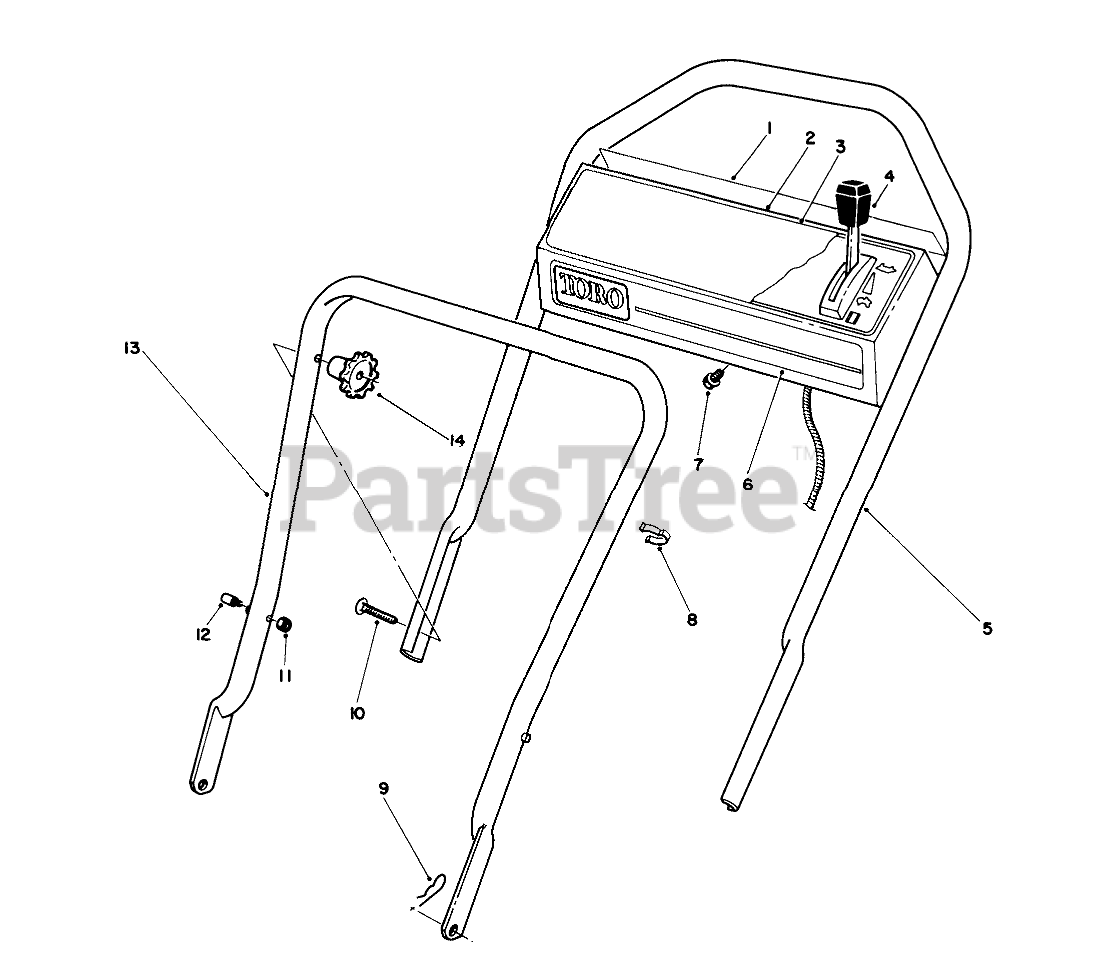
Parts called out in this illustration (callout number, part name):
1	DECAL - PANEL, REAR
2	Panel-Control (Incl.Ref. #1, 3 & 6)
3	Decal-Instruction
4	THROTTLE CONTROL - R&S
5	Handle-Upper
6	DECAL - TORO PANEL
7	SCREW-HWHTF
8	BOWDEN CLIP
9	PIN-COTTER, HAIR
10	5/16-18 X 2 HNDLE SCREW
11	NUT-LOCK, NI
12	HANDLE PIN
13	LOWER HANDLE ASM
